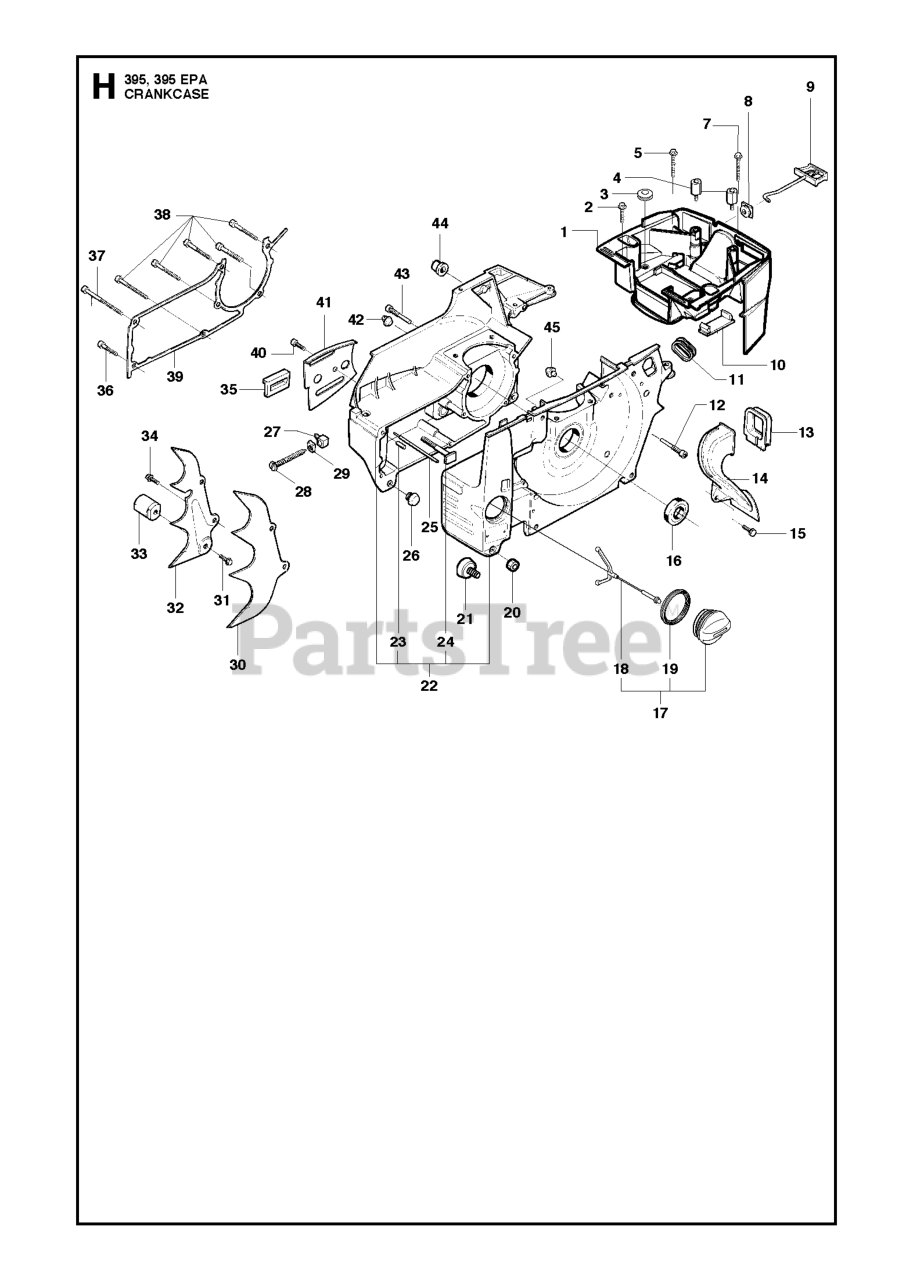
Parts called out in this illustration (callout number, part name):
4	VIBRATION ABSORBER
9	CHOKE CONTROL
16	SEALING RING
17	TANK CAP
21	VIBRATION DAMPER
25	OIL TANK VENT
28	SCREW CHAIN TENSIONER
29	COUPLING (10 CNT)
30	SPIKE INNER
33	CHAIN CATCHER
35	CHAIN GUIDE
36	SCREW MC6S 5X25
37	SCREW MC6S 5X60
38	SCREW MC6S 5X35
42	RUBBER BUMPER
45	RUBBER BUMPER
